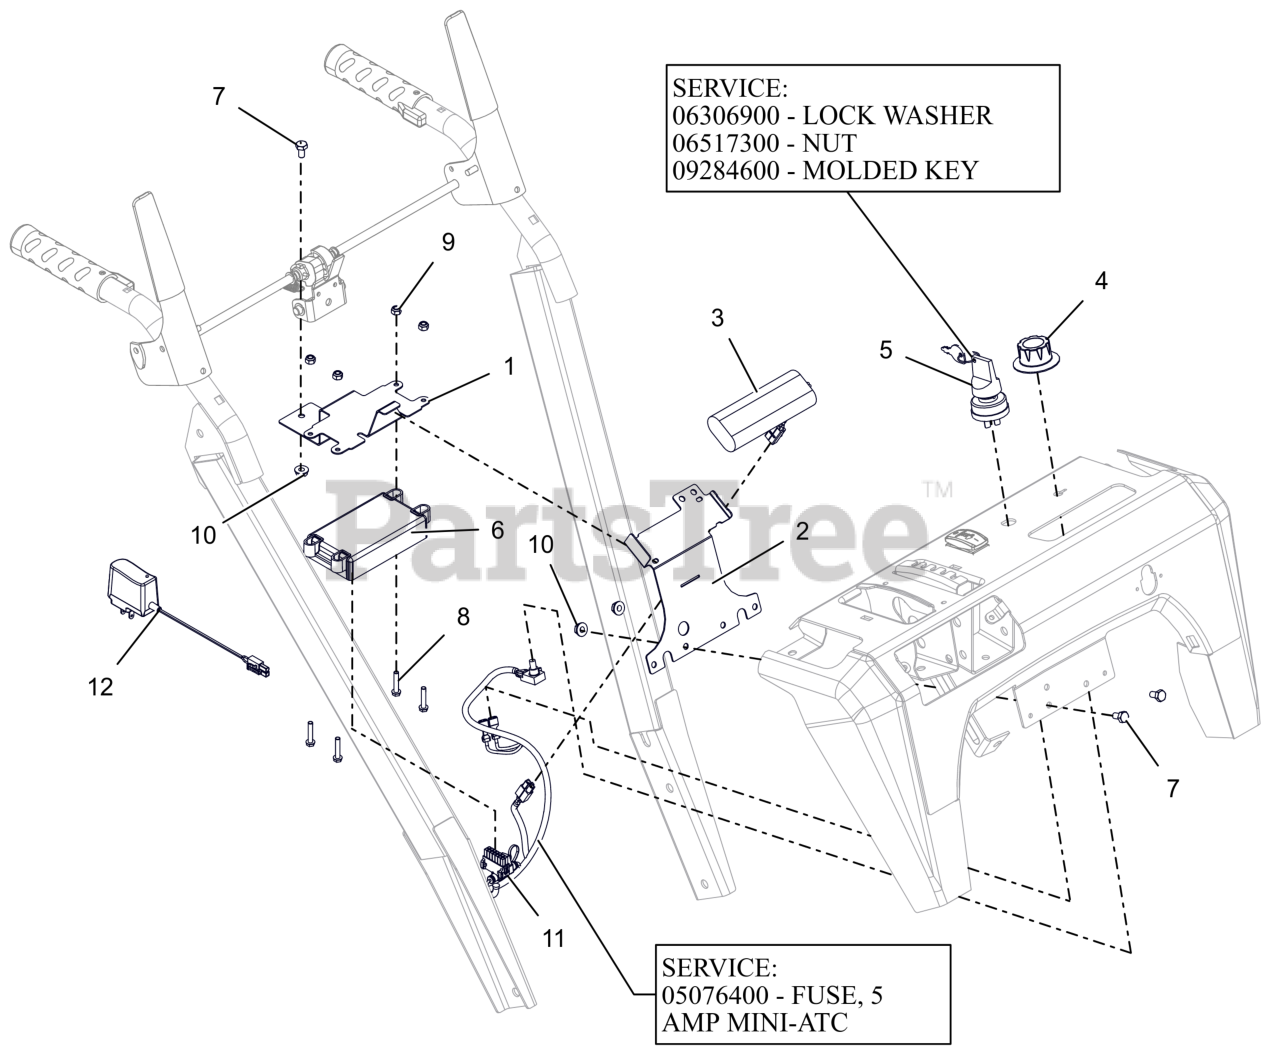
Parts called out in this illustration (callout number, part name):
1	BRACKET, ENGINE EFI-LCT LOWER
2	BRACKET, ENGINE EFI-LCT UPPER
3	BATTERY, SNOW EFI - 7.2V
4	KNOB, CONTROL - 2.063 ID
5	IGNITION SWITCH ASM - 2 POS
5	WSHR-LK-INT .625X.045 YWZC
5	NUT-PANEL .625-32 GRECO
5	KEY W/ SHIELD
6	ECU SERVICE LCT/CSI - 420CC
7	BLT,HEX .25-20X.50 G5 ZCC
8	BLT, HWH #10-24X1.00 ZCC
9	NUT-LK-NYL #10-24 G2 ZCC
10	NUT-LK-TOP-FLG .250-20 GF ZCC
11	HARNESS,WIRE - EFI ECU
11	FUSE, 5 AMP MINI-ATC
12	CHARGER, BATTERY - EFI 7.2V
